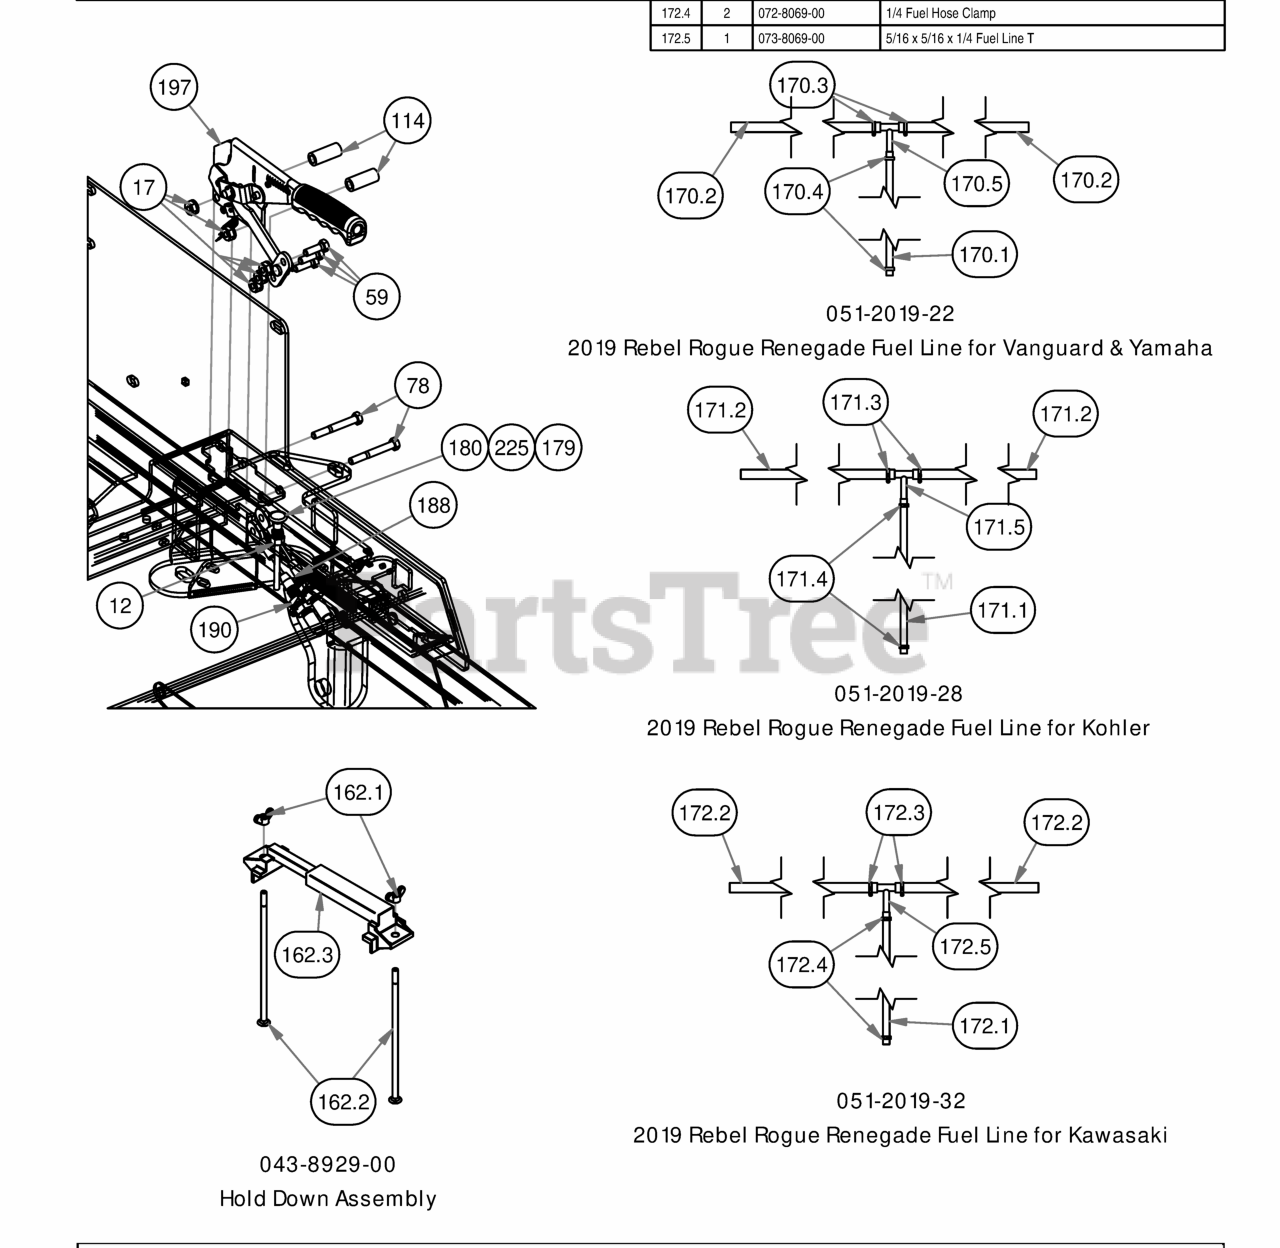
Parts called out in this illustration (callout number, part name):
12	3/8" Fine Threaded Jam Nut
17	5/16-18 Nylon Flange Nut
59	5/16" x 1" Bolt
78	5/16" x 2 1/2" Bolt
114	2019 Outlaw Brake Handle Spacer .625 x 1.5
162.1	1/4" Wing Nut
162.2	1/4-20 X 8 Carriage Bolt
162.3	Battery Hold Down
170.1	1/4" Fuel Line Hose
170.2	5/16" fuel line hose
170.3	5/16 Fuel Line Clamp
170.4	1/4 Fuel Hose Clamp
170.5	5/16 x 5/16 x 1/4 Fuel Line T
171.1	1/4" Fuel Line Hose
171.2	5/16" fuel line hose
171.3	5/16 Fuel Line Clamp
171.4	1/4 Fuel Hose Clamp
171.5	5/16 x 5/16 x 1/4 Fuel Line T
172.1	1/4" Fuel Line Hose
172.2	5/16" fuel line hose
172.3	5/16 Fuel Line Clamp
172.4	1/4 Fuel Hose Clamp
172.5	5/16 x 5/16 x 1/4 Fuel Line T
180	Choke for 36Hp Vanguard & FX1000 Kawasaki
188	2019 Short Brake Cable-Suspension Models
190	2019 Long Brake Cable-Renegade, Rogue
197	2019 Brake Handle Assembly
225	Code Indicator Light
